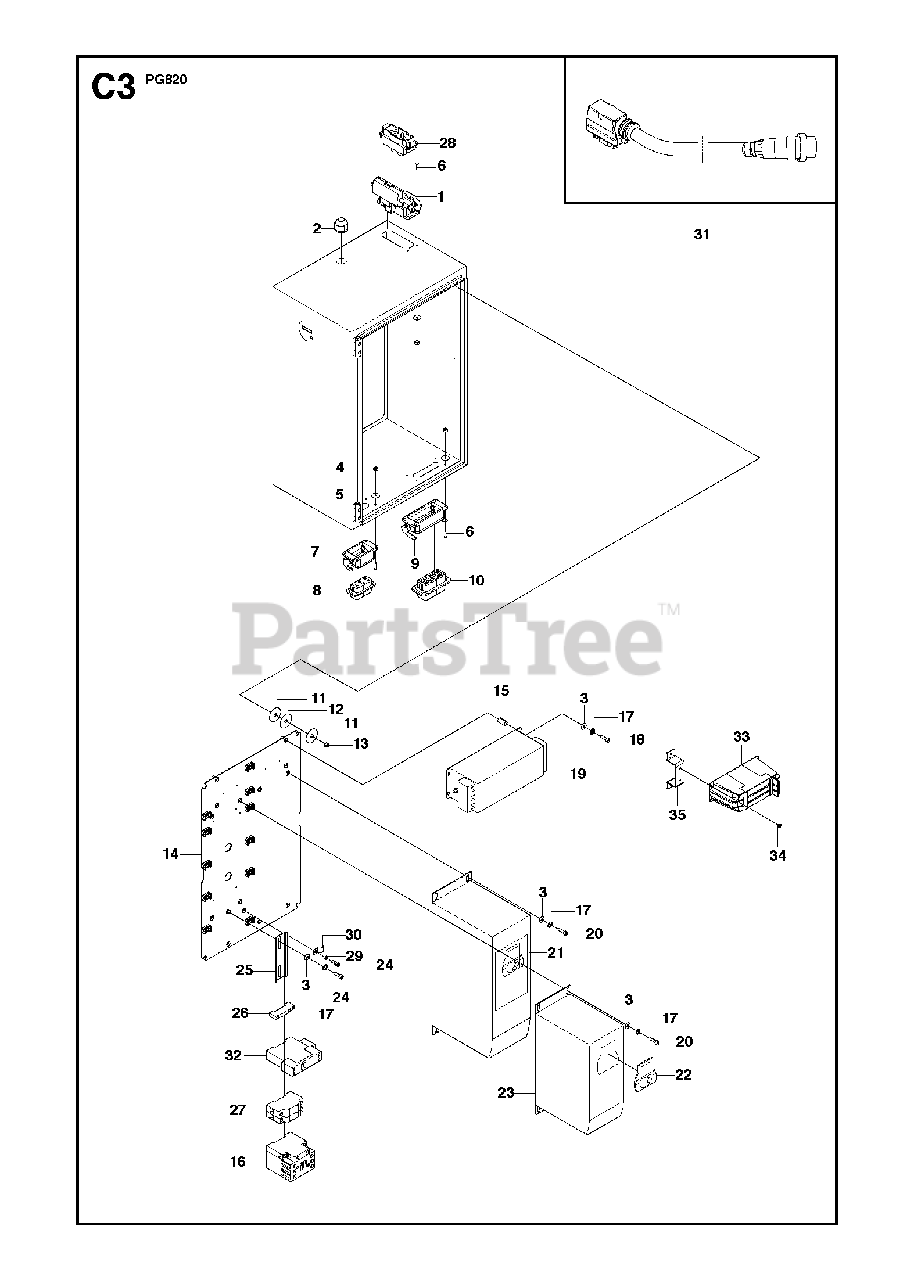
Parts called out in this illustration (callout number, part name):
4	HEXAGON LOCKING NUT
6	SCREW CRPANM
13	HEXAGON LOCKING NUT
21	FREQUENCY INVERTERJP, 220 V
23	FREQUENCY INVERTERJP, 220 V
